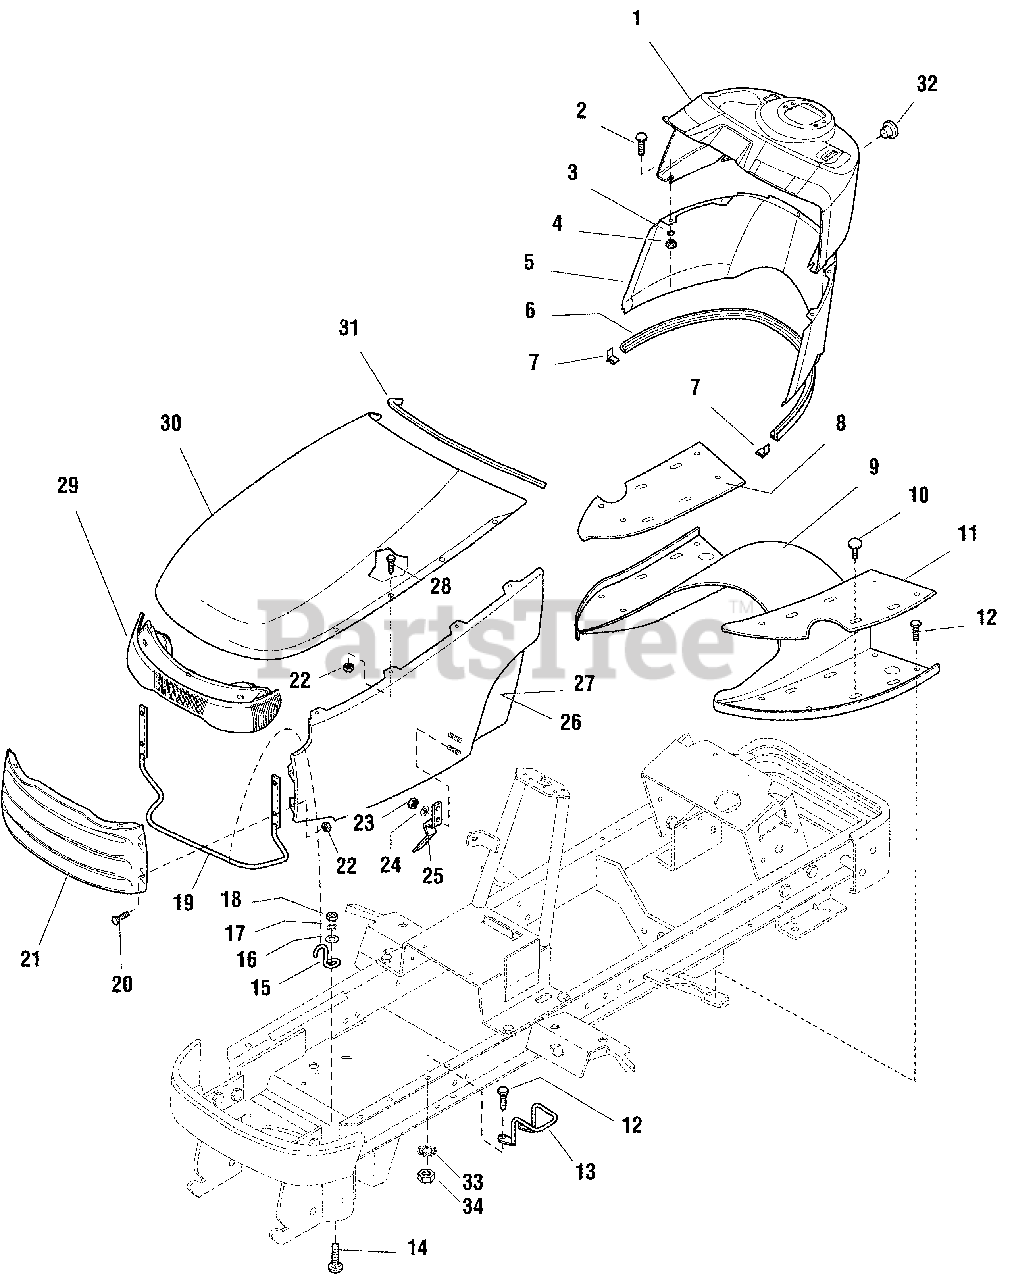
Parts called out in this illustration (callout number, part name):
1	DASH, Upper
2	CARRIAGE BOLT, 1/4-20 x 5/8
3	LOCKWASHER, 1/4
4	NUT, Hex, 1/4-20
5	DASH, Lower
6	EDGING, Dash
8	PAD, Footrest, RH
10	FASTENER, Panel
11	PAD, Footrest, LH
12	CAPSCREW, Hex Hd, Taptite, 1/4-20 x 1/2
13	ROD, Hood Latch
14	CARRIAGE BOLT, 5/16-18 x 1
15	ROD, Hood Latch Pivot
16	WASHER, Flat
17	LOCKWASHER, 5/16
18	NUT, Hex, Full, 5/16-18
19	ROD, Hood Hinge
20	CAPSCREW, Hex Hd, Whizlock, 1/4-20 x 3/4
21	GRILL (Orange)
21	GRILL (Red)
22	NUT, Hex ,Whizlock, 1/4-20
23	NUT, Hex, Nylon Lock, #10-24
25	CLIP, Hood Latch
26	SIDE PANEL, LH (Orange)
26	SIDE PANEL, LH (Red)
27	SIDE PANEL, RH (Orange)
27	SIDE PANEL, RH (Red)
28	CAPSCREW, Hex Hd, Whizlock, 1/4-20 x 5/8
29	HEADLIGHT BEZEL
30	HOOD (Orange)
31	EDGING, Hood
33	LOCKWASHER, External Tooth
34	NUT, KEPS 1/4-20
